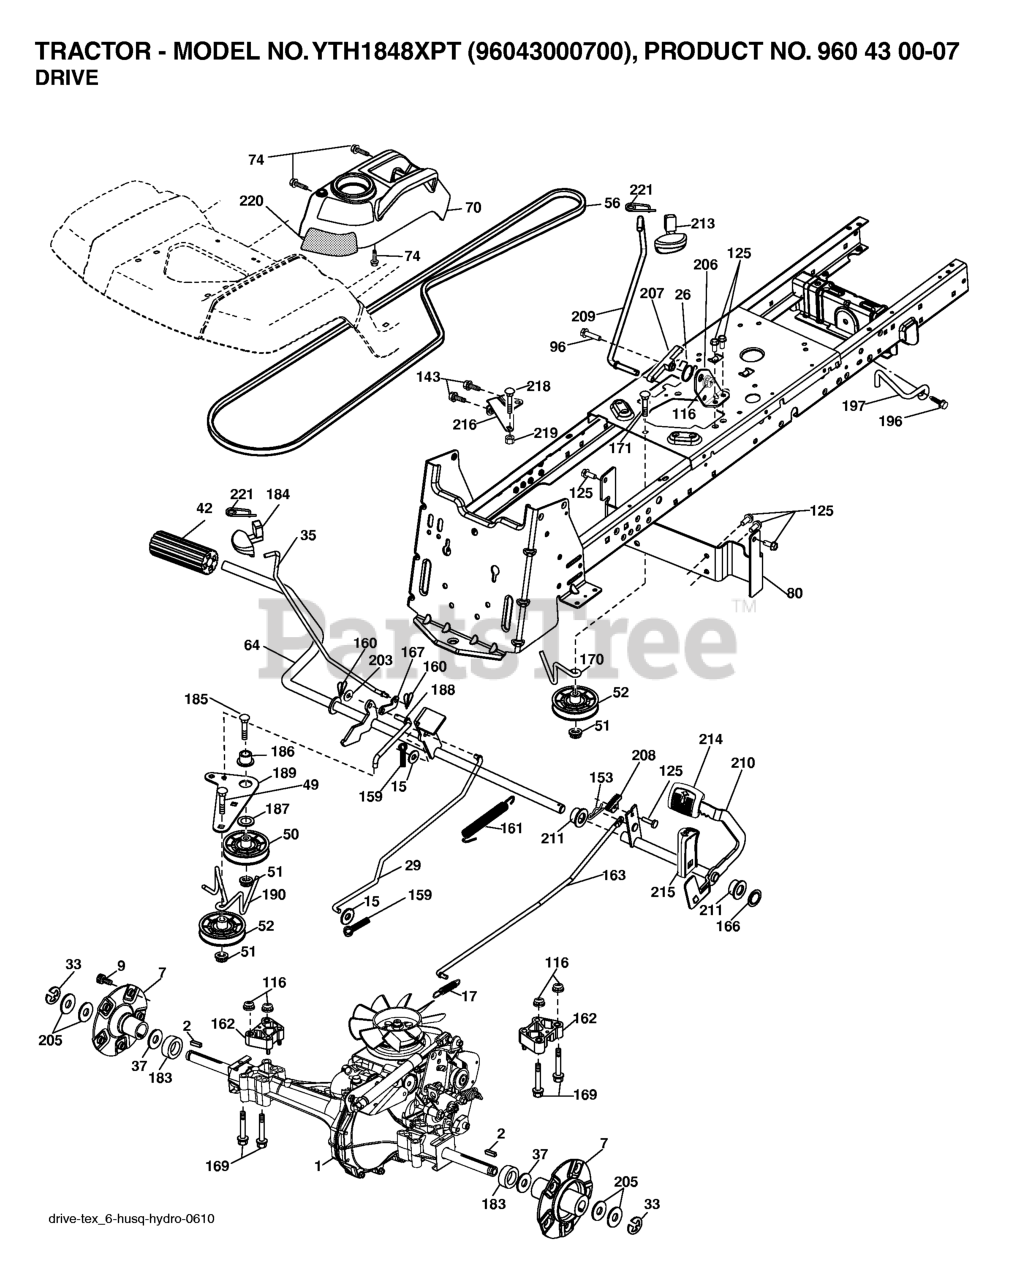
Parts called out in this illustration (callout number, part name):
2	KEY.SQUARE.187X2.500
7	HUB.ASM.WHEEL.REAR.22"
15	WASHER
17	SPRING.BRAKE.HG3000/3500
26	SPRING.RETURN.CRUISE
29	ROD.BRAKE.0610.PEDAL.CONTROL
35	ROD.BRAKE.PARKING.GT.H
42	PEDAL COVER T
50	IDLER.FLAT.910.OFFSET
51	NUT LOCK FLG 3/8-16 UNC
52	IDLER.V-GROOVE.910.OFFSET
64	SHAFT.ASM.PEDAL.BRK.CNTR
70	RP CONSOLE.ASM.PCH.W/TB
74	SCREW.HI-LO.CONSOLE
80	BRKT.STRP.TRQ.LT.HYD.C
96	BOLT
106	O-RING KIT 70110
107	LINE.VENT.HYDRO-GEAR
108	CAP, VENT ASSY
116	NUT LOCK HEX FLANGE 5/16-18
121	BRKT.STRP.TRQ.LT.HYD.C
125	SCREW
148	SCREW, 3/8-16X3/4
153	RETAINER M
159	COTTER PIN
160	RETAINER CLIP
161	SPRING.RETURN.CLUTCH.2006
162	SPACER.TRANSAXLE.18&22
163	ROD.PEDAL.CONTROL.0510
166	NUT.PUSH.625.2006
167	LATCH.BRAKE.SPRING
169	BOLT.HEX.FLNG.5/16-18X3.75
170	KEEPER.V-IDLER.CENTER.
171	BOLT CARRIAGE
183	SPACER.SPLIT.800X.350
186	SPACER.RETAINER
187	WASHER 12/32X2X10GA
188	RP.LINK.CLUTCH.GROUND.DRIVE
189	BELLCRANK.GROUND.DRIVE.TEX.
190	KEEPER.BELLCRANK.DRIVE
196	SCREW 3/8-16X1
197	LINK.CLUTCH.ANIT-ROTAT
200	NUT.CENTERLOCK.5/16-
201	BOLT SHOULDER 5/16-18 UNC
203	WASHER
206	BRKT.MOUNT.LATCH.CRUIS
207	LATCH.CONTROL.CRUISE
208	GEAR.SECTOR.CONTROL.CR
210	ROCKER.ASM.PEDAL.CONTR
211	BEARING.NYLON
214	PEDAL.FORWARD.TEX.GT.4
215	PEDAL.REVERSE.TEX.GT.4
216	BRACKET.PULLEY.IDLER.W/TEX
217	SCREW, 5/16-18 X 1/2
218	BOLT.5/16-18X1-1/4 FULL.THREAD
219	SPACER.FENDER
